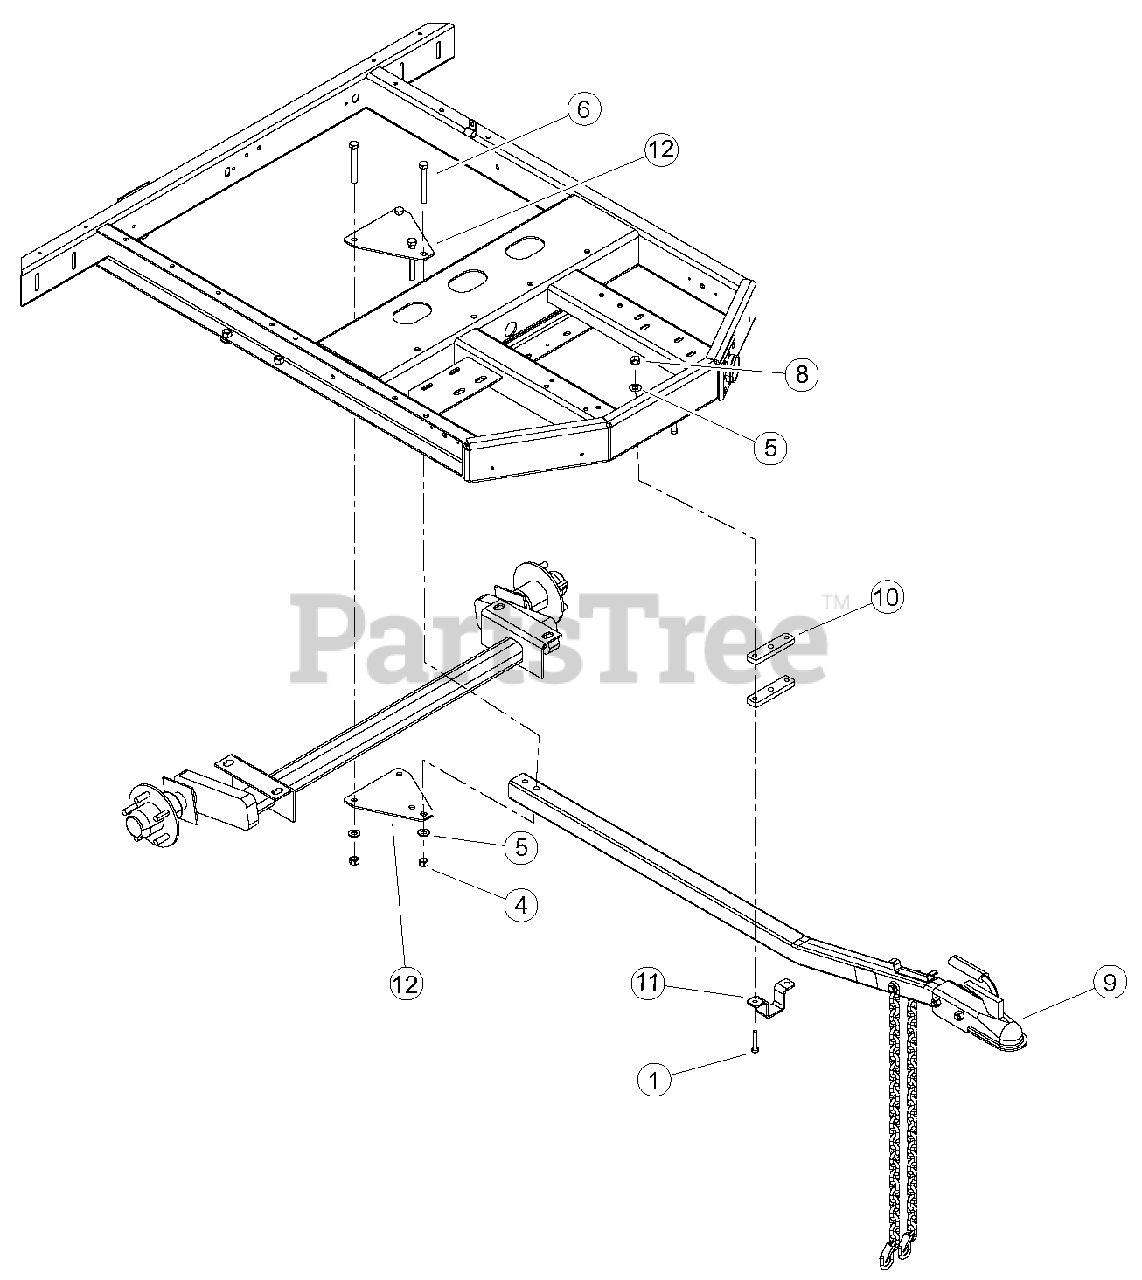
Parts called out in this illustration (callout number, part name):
1	BOLT 3/8*2 GR5 HEX CAPSCREW ZP
2	BOLT, 1/2X2 GR5 HEX CAPSCREW ZP (NOT PICTURED)
3	NUT, 1/2" HEX NC ZP (NOT PICTURED)
4	NUT, 1/2" CENTERLOCK GRB ZP
5	WASHER 1/2"SAE FLAT ZP(56PC/LB
6	BOLT 1/2 X 4 HEX CPS G5 ZP
7	CLAMP, 9/16 COATED (NOT PICTURED)
8	NUT, 3/8-16 NYLOCK FLANGE
9	ASSEMBLY, 6" HITCH POLE XE
10	SPACER, HITCH POLE XE MODEL
11	STRAP, HITCH POLE XE MODEL
12	PLATE, AXLE SAFETY
